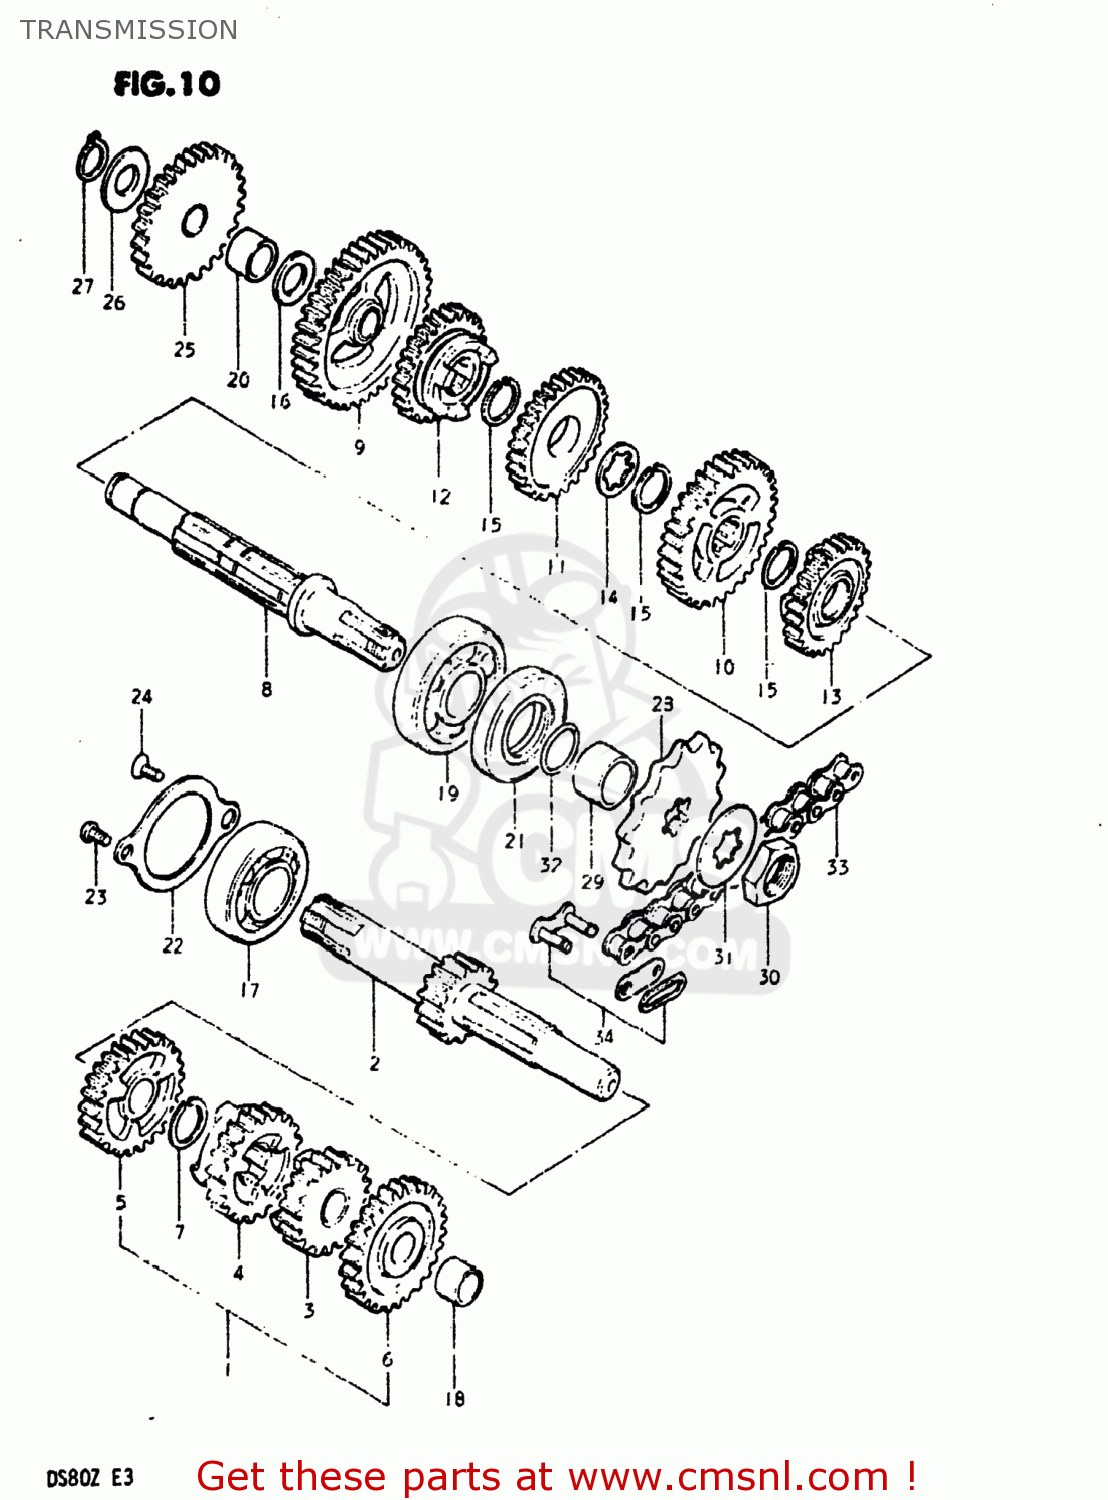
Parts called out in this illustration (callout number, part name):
1	SHAFT,COUNTER
2	SHAFT,COUNTER(NT:13)
3	GEAR,2ND DRIVE(NT:19)
4	GEAR,3RD DRIVE(NT:22)
5	GEAR,4TH DRIVE(NT:24)
6	GEAR,FIFTH DRIVE
7	CIRCLIP
8	SHAFT,DRIVE
9	GEAR,1ST DRIVEN(NT:35)
10	GEAR,2ND DRIVEN(NT:32)
11	GEAR,3RD DRIVEN(NT:29)
12	GEAR,4TH DRIVEN(NT:36)
13	GEAR,5TH DRIVEN(NT:24)
14	WASHER(13X24X1)
15	CIRCLIP
16	WASHER,LOCK
17	BEARING
18	BUSH
19	BEARING
20	BUSH
21	SEAL,OIL(21X40X6)
22	RETAINER,CNTR SHAFT BEARING
23	SCREW
24	SCREW
25	GEAR,KICK STARTER IDLE
26	WASHER
27	CIRCLIP
28	SPROCKET,ENGINE
29	SPACER(17X21X13)
30	NUT
31	WASHER,LOCK
32	O RING(D:1,ID:16.8)
33	CHAIN ASSEMBLY,DRIVE
34	JOINT ASSEMBLY,CHAIN
